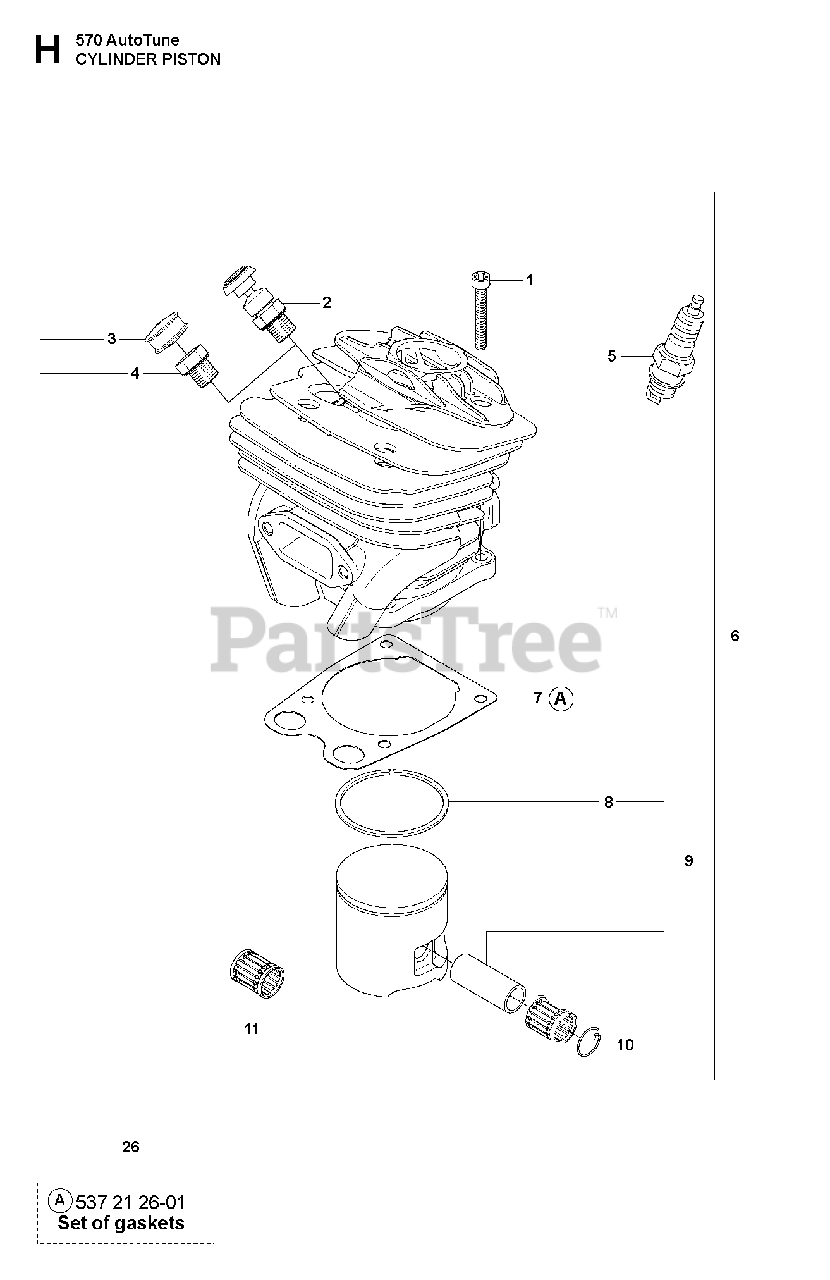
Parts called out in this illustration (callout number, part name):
1	SCREW MC6S 5X25
2	VALVE
3	PLUG
4	CYLINDER PLUG
5	SPARK PLUG RCJ7Y
7	GASKET
8	PISTON RING
9	PISTON 49 MM
10	WRIST PIN CLIP
11	SUPPORT BUSHING
26	GASKET SET
